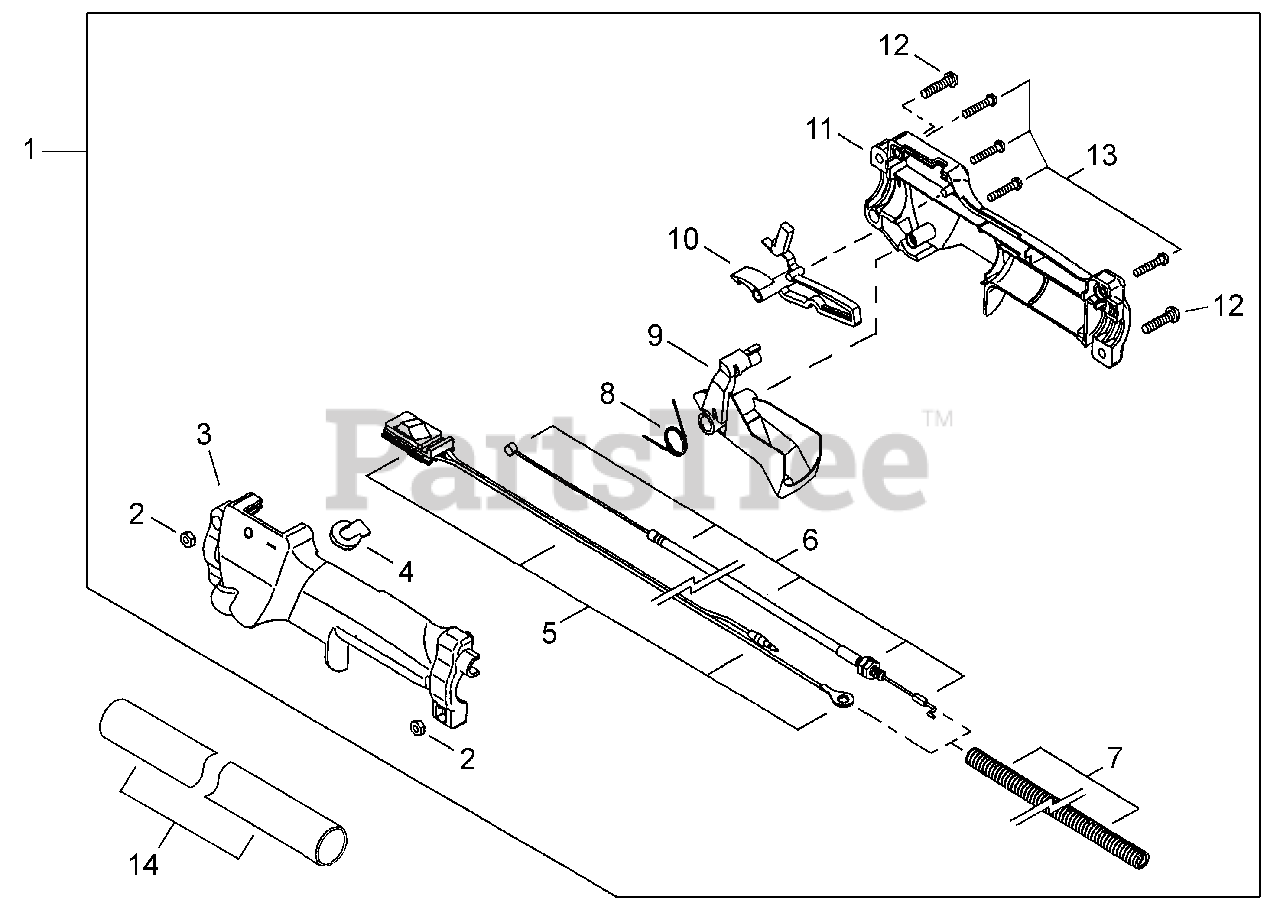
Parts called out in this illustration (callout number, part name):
1	THROTTLE CONTROL ASSY
3	CONTROL HANDLE - LEFT
5	SWITCH, ON-OFF
6	CABLE, THROTTLE
7	TUBE, PLASTIC PROTECTIVE
8	SPRING, THROTTLE RETURN
9	TRIGGER, THROTTLE
10	LEVER, THROTTLE LOCKOUT
11	CONTROL HANDLE - RIGHT
12	SCREW M5×20
13	SCREW, TAPPING M4×20
